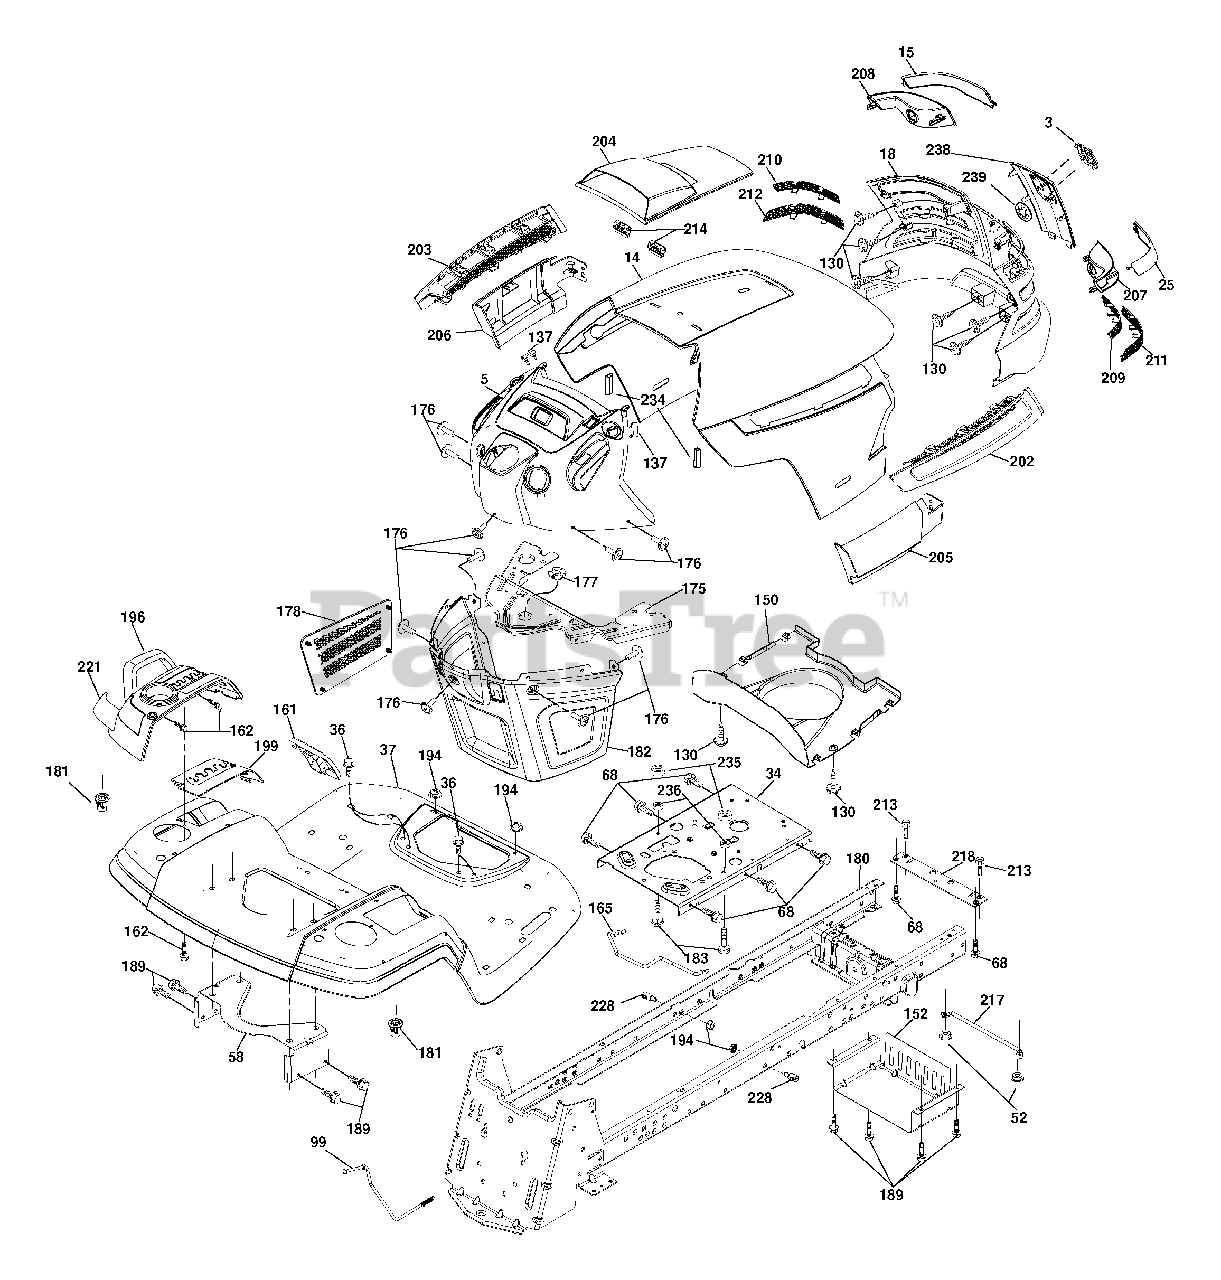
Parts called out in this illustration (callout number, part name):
3	Logo Husq
14	Hood
34	Plate Engine
36	Screw 5/16-18 x 3/4
37	Fender
52	Nut Lock 5/16-18
58	Bracket Fender
68	Screw 5/16-18 x 1/2
99	Rod Bypass Asm.
130	Screw 10 x 3/4 Single Lead Hex
137	Bumper Dash
150	Duct Heat Hood
152	Shield Browning/Debris
161	Console Fuel Window
162	Screw Hex Wsh Hi-Lo 1/4 x 1/2
165	Bracket Support Tank
175	Crossmember
176	Screw 10-24 x 5/8 Rnd Qdrx
177	Bushing Steering
178	Cargo Asm. Net
180	Chassis
181	Bushing Mtg. Fender Crgo.
182	Dash Lower
183	Bolt 5/16-18 x 1-1/4
189	Screw 5/16-18 x 3/4
194	Nut Lock Hex Flange 5/16-18
196	Console Asm. Deck Lift
199	Plate Deck Lift
202	Vent Side Hood RH
203	Vent Side Hood LH
204	Vent Asm Hood Top
205	Skirt Hood Side RH
206	Skirt Hood Side LH
209	Insert Hex Top RH
210	Insert Hex Top LH
211	Insert Hex Bottom RH
212	Insert Hex Bottom LH
213	Bolt Hex Hd 5/16-18 unc x 3/4
214	Clip Retainer
217	Rod Pivot
221	Reflector LH
228	Stud Fastner
234	Bumper Hood
235	Spacer Fender
236	Nut Lock 5/16-18 unc
